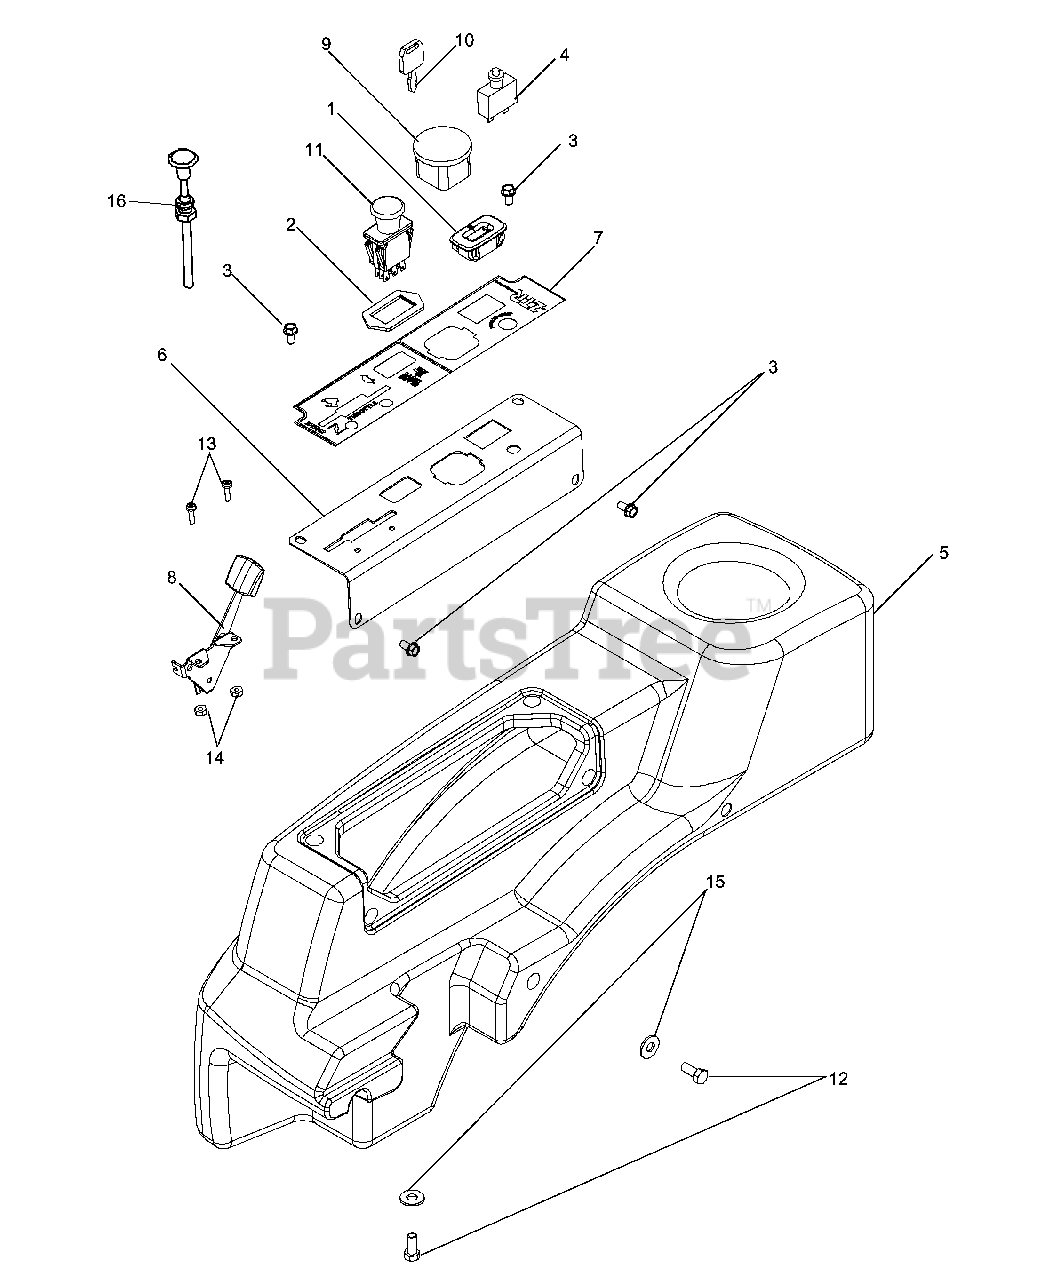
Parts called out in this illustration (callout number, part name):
1	HOUR METER
2	PTO SWITCH RETAINER
3	1/4-20 X 1/2 HWH FORM SCR H
4	CIRCUIT BREAKER W58XB1A4A15
6	CONTROL PANEL
7	DECAL CONTROL PANEL
8	CABLE THROTTLE
9	IGNITION SWITCH
10	KEY
11	SWITCH, BLADE
12	HCS 5/16C X 3/4
13	SCREW #10-24 X 5/8
14	NUT 10-24 NYLOC
15	FLAT WASHER 5/16 SAE
